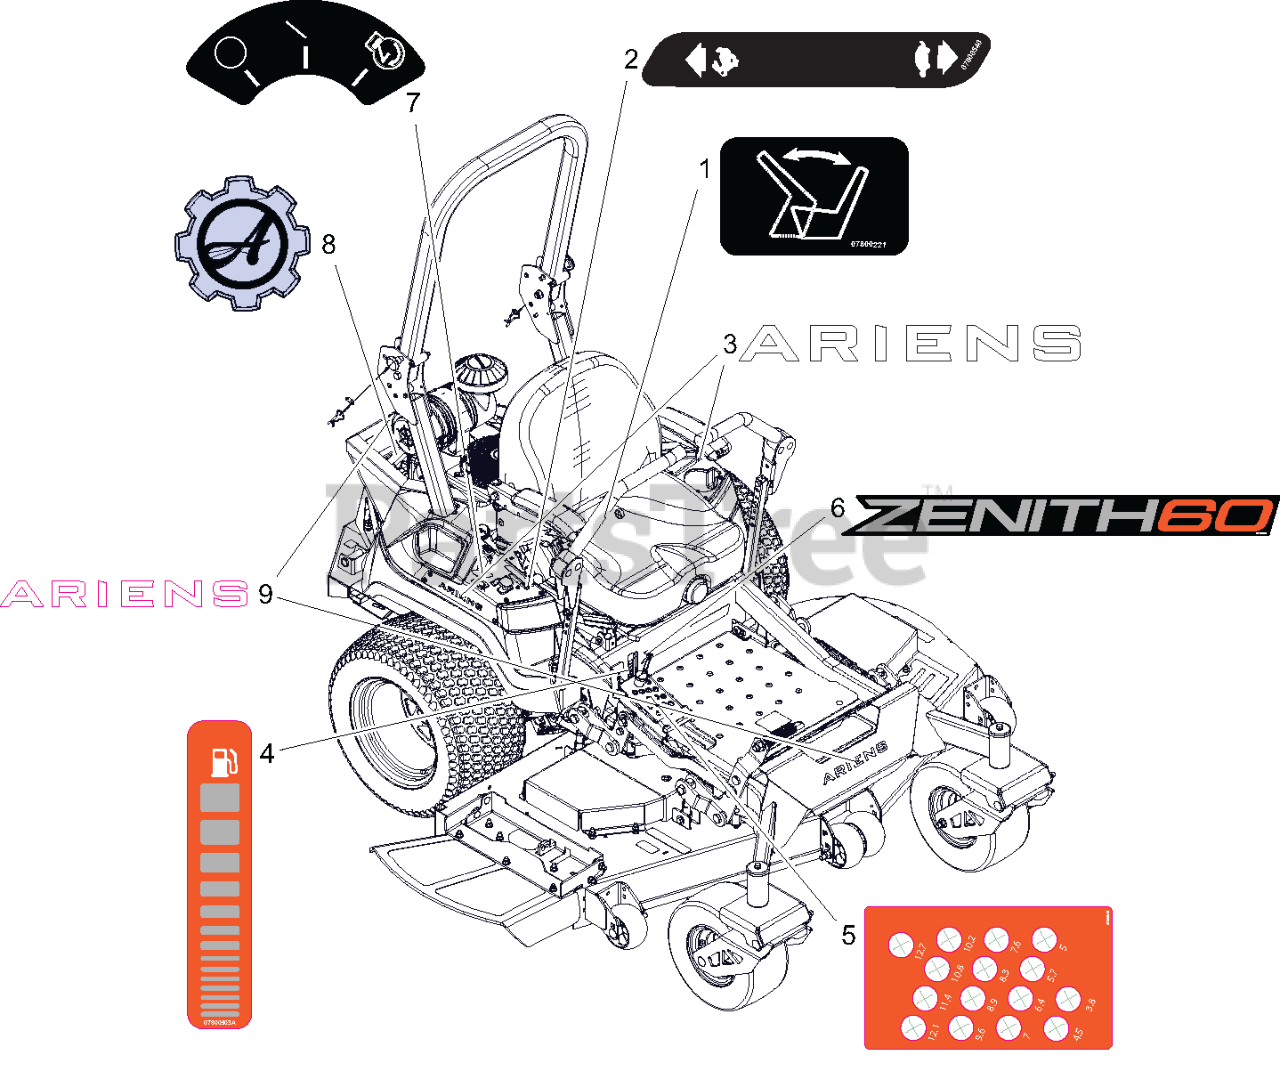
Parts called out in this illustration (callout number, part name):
1	DECAL - SEAT RELEASE
2	DECAL, DASH DECAL
3	DECAL, ARIENS (6.50")
4	DECAL, ARIENS FUEL LEVEL
5	DECAL, APEX HOC METRIC
6	DECAL, ZENITH 60
7	DECAL, KEYSWITCH
8	DECAL- ARIENS GEAR BADGE
9	DECAL - ARIENS 9.625"
